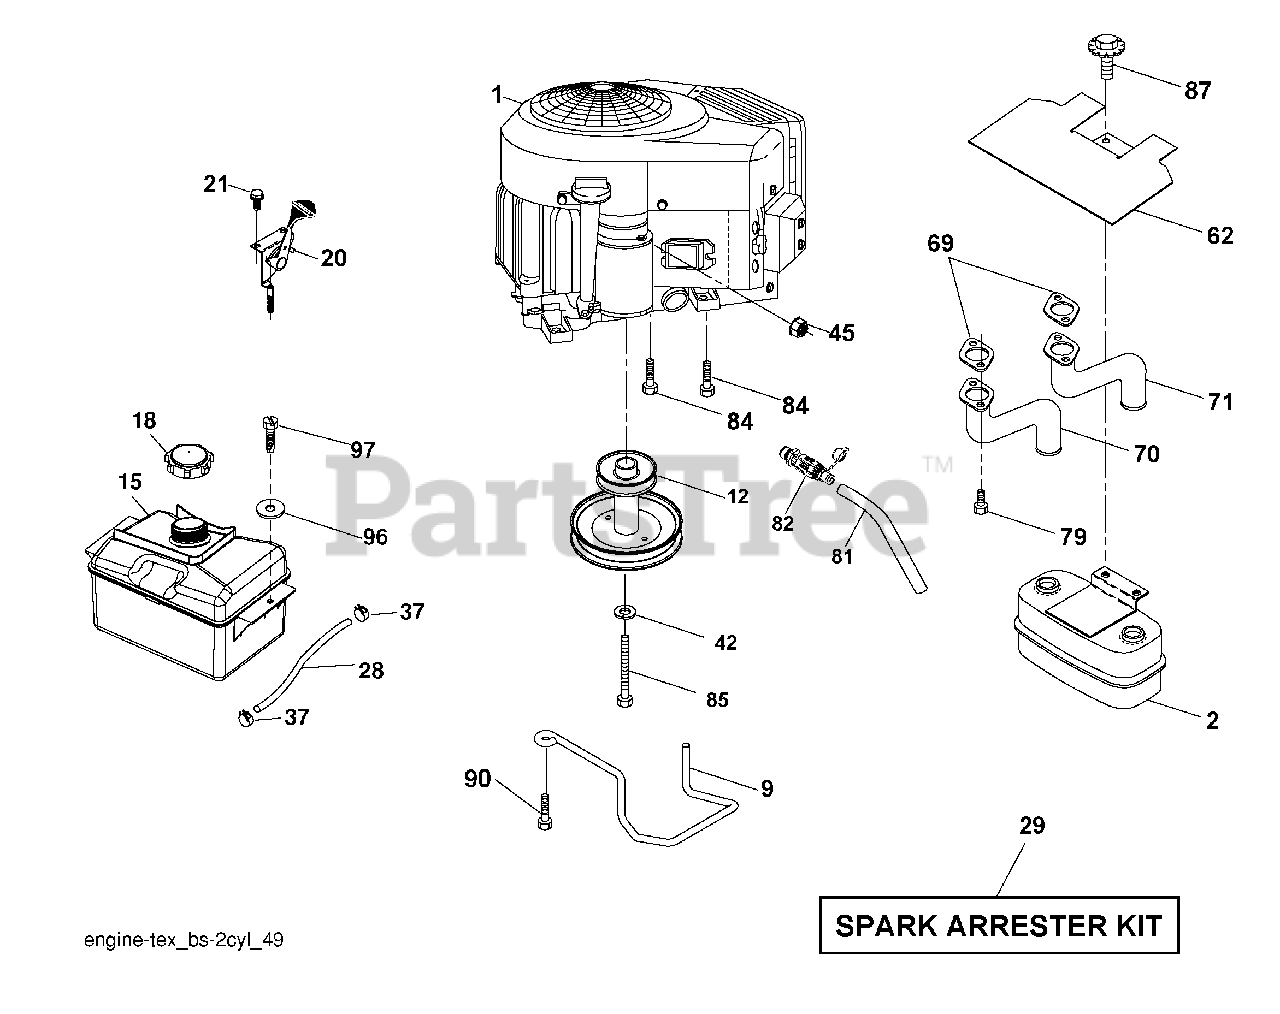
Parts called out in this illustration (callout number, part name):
9	Keeper Belt Engine
12	Pulley Engine
15	Tank Fuel
18	Cap Asm
20	Control Throttle
21	Screw #10 x 0.750 BOS Thread
28	Fuel Line
29	Spark Arrester Kit
37	Clamp Hose
42	Washer Lock 7/16
45	Nut Keps Hex 1/4-20 unc
62	Shield Heat
70	Exhaust Tube LH
71	Exhaust Tube RH
79	Screw 5/16-18 x 1
81	Tube Drain Oil Easy
82	Valve Drain Oil
83	Bolt 5/16-18 unc x 3/4 w/sems
84	Screw 3/8-16 x 1/4
85	Bolt Hex 7/16-20 x 4 Gr. 5
90	Screw 3/8-16 x 1
96	Washer 9/32 x 7/8 x 16 Ga.
97	Screw 1/4-20 x 3/4
